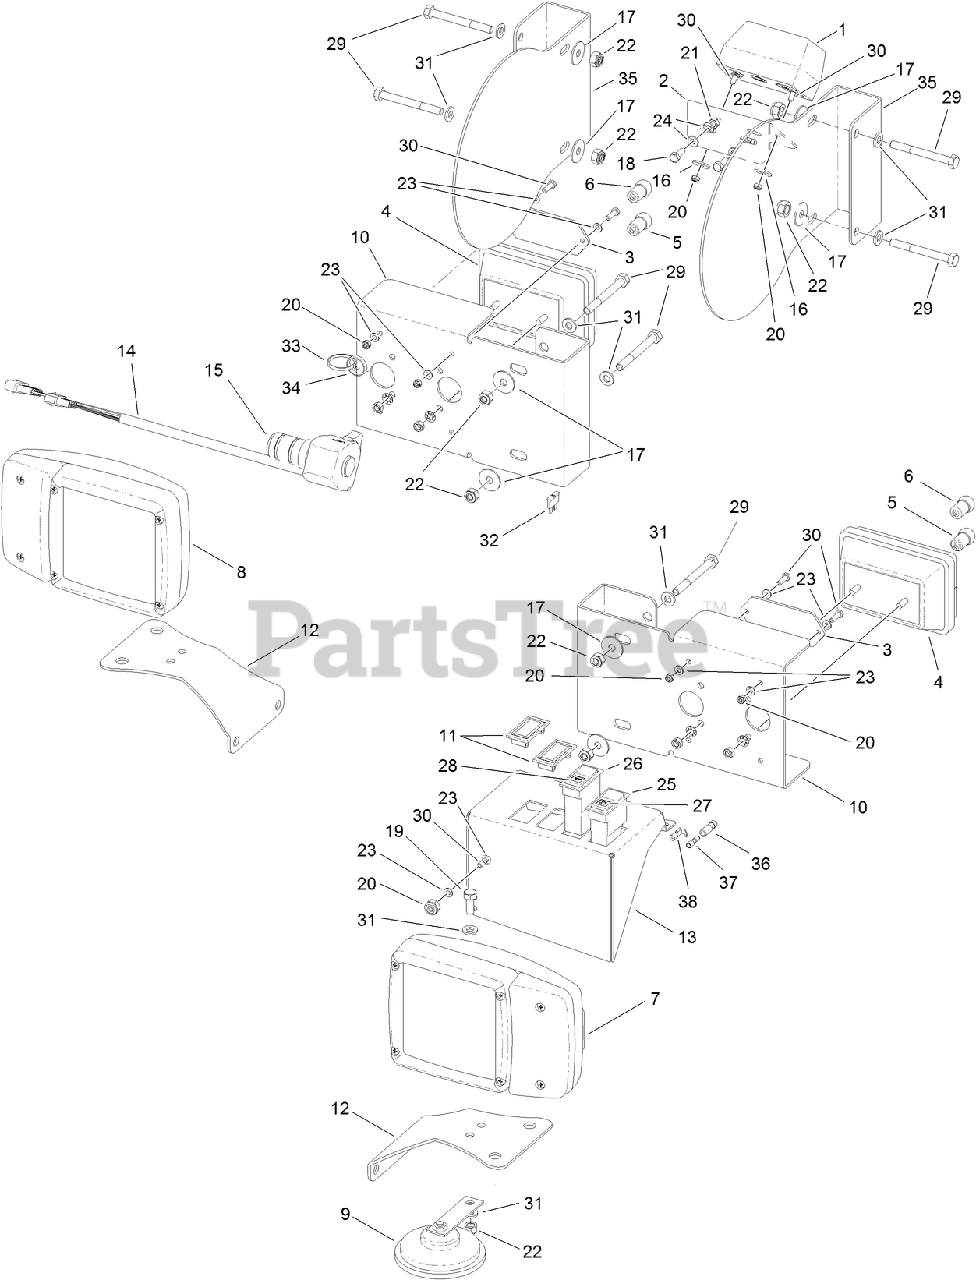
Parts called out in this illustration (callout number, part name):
1	LAMP ASM
3	REFLECTOR-REFLEX, RED
4	LAMP-INDICATOR, REAR
5	BULB-INDICATOR
7	HEADLAMP-INDICATOR, LH
8	HEADLAMP-INDICATOR, RH
10	BRACKET-LIGHT, REAR
11	BLANK-SWITCH
12	BRACKET-LIGHT, FRONT
13	PANEL-SWITCH
14	SWITCH COMBINATION ASM
15	ADAPTOR-SWITCH
16	WASHER
17	WASHER-PLAIN
18	SCREW-HH
19	SCREW-HH
20	NUT-NYLOC
21	NUT-NYLOC
22	NUT-HEX, NI
23	WASHER
24	WASHER-PLAIN
25	SWITCH-DIP/MAIN
26	SWITCH-HAZARD, WARNING
27	LENS-MAIN, LIGHT
28	LENS-HAZARD, WARNING
30	SCREW-HH
31	WASHER-PLAIN
32	FUSE-30A
33	TIE-CABLE
34	TIE-CABLE
35	BRACKET-SPEED DECAL, SIDE
36	CRIMP-FEMALE, BULLET
37	CRIMP-MALE, BULLET
38	CRIMP-TERM., PIGGYBACK RED
